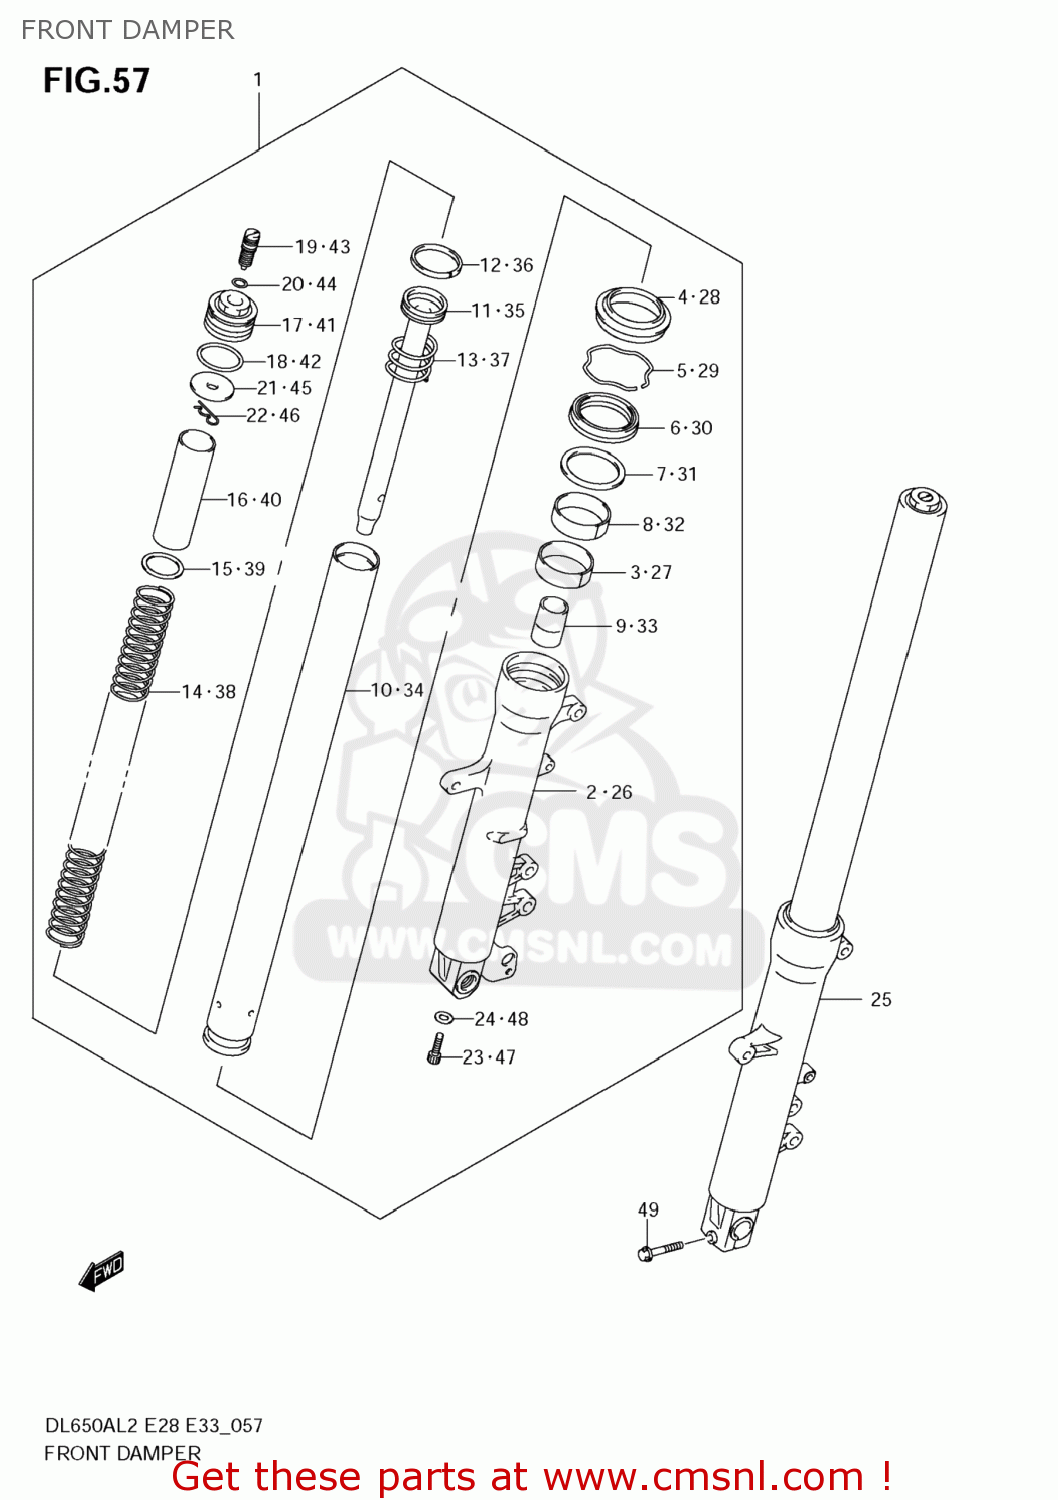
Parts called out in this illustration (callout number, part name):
1	DAMPER ASSY,FR FORK,R
2	TUBE,OUTER,R
3	BUSH,SLIDE
4	SEAL,DUST
5	CIRCLIP,FORK OIL SEAL
6	SEAL,OIL
7	SPACER,SEAL
8	BUSH,GUIDE
9	PIECE,OIL LOCK
10	PIPE,FORK
11	PIPE,SEAT
12	RING,PISTON
13	SPRING,REBOUND
14	SPRING,FR
15	SEAT,SPRING LWR
16	COLLAR,SPRING
17	BOLT,FORK
18	O RING
19	ADJUSTER BOLT,SPRING
20	O RING
21	SEAT,SPRING
22	PIN,SEAT SPRING
23	BOLT(8X27)
24	GASKET (NAS)
25	DAMPER ASSY,FR FORK,L
26	TUBE,OUTER,L
27	BUSH,SLIDE
28	SEAL,DUST
29	CIRCLIP,FORK OIL SEAL
30	SEAL,OIL
31	SPACER,SEAL
32	BUSH,GUIDE
33	PIECE,OIL LOCK
34	PIPE,FORK
35	PIPE,SEAT
36	RING,PISTON
37	SPRING,REBOUND
38	SPRING,FR
39	SEAT,SPRING LWR
40	COLLAR,SPRING
41	BOLT,FORK
42	O RING
43	ADJUSTER BOLT,SPRING
44	O RING
45	SEAT,SPRING
46	PIN,SEAT SPRING
47	BOLT(8X27)
48	GASKET (NAS)
49	BOLT,HOLDER AXLE(8X40)
